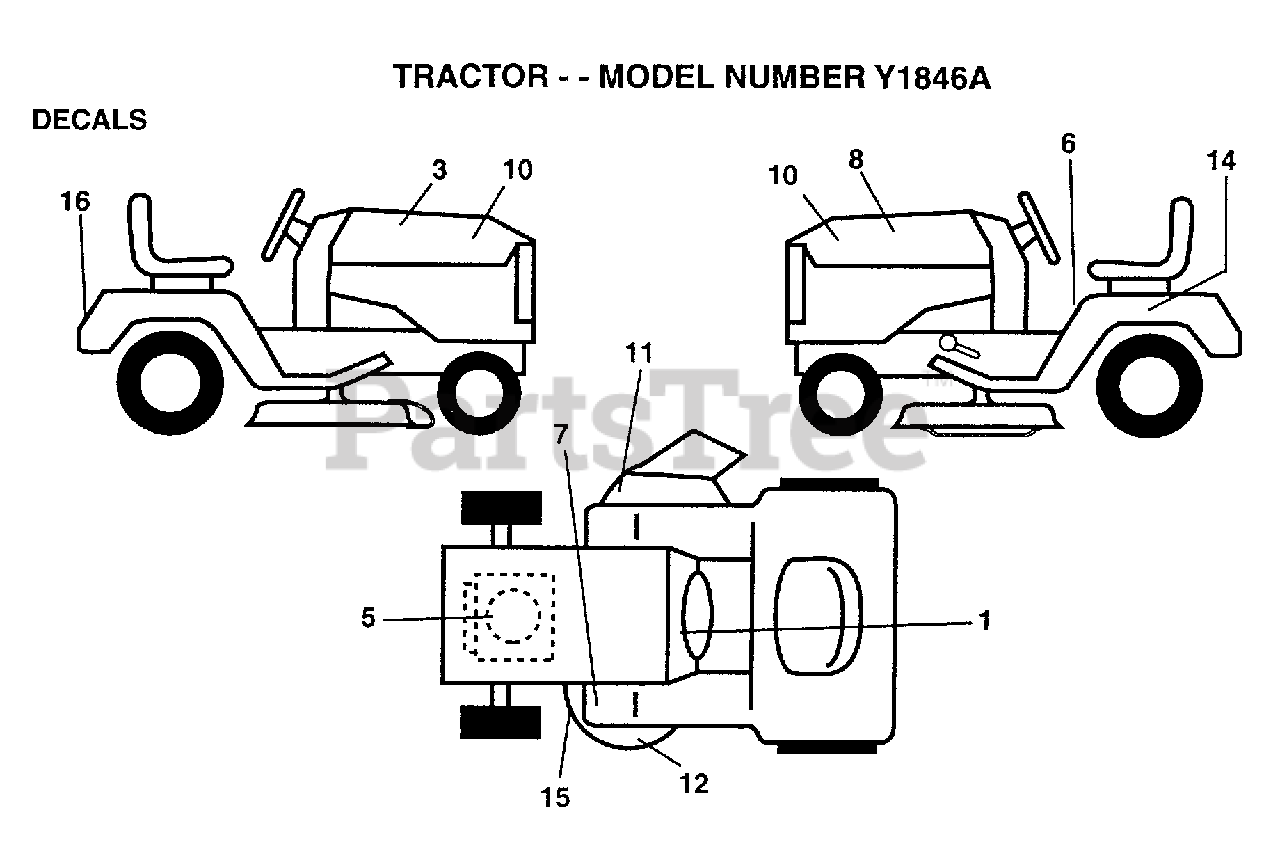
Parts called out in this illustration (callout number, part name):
1	DECAL DASH INS OP
3	DECAL.HD.RH.
5	DECAL ENGINE
6	DECAL CAUTION
7	DECAL T
8	DECAL.HD.LH.
10	DECAL PANEL SIDE
11	"DECAL, WARNING"
14	DECAL.BTRY.DANGER
15	"DECAL.V.BELT.44"""
